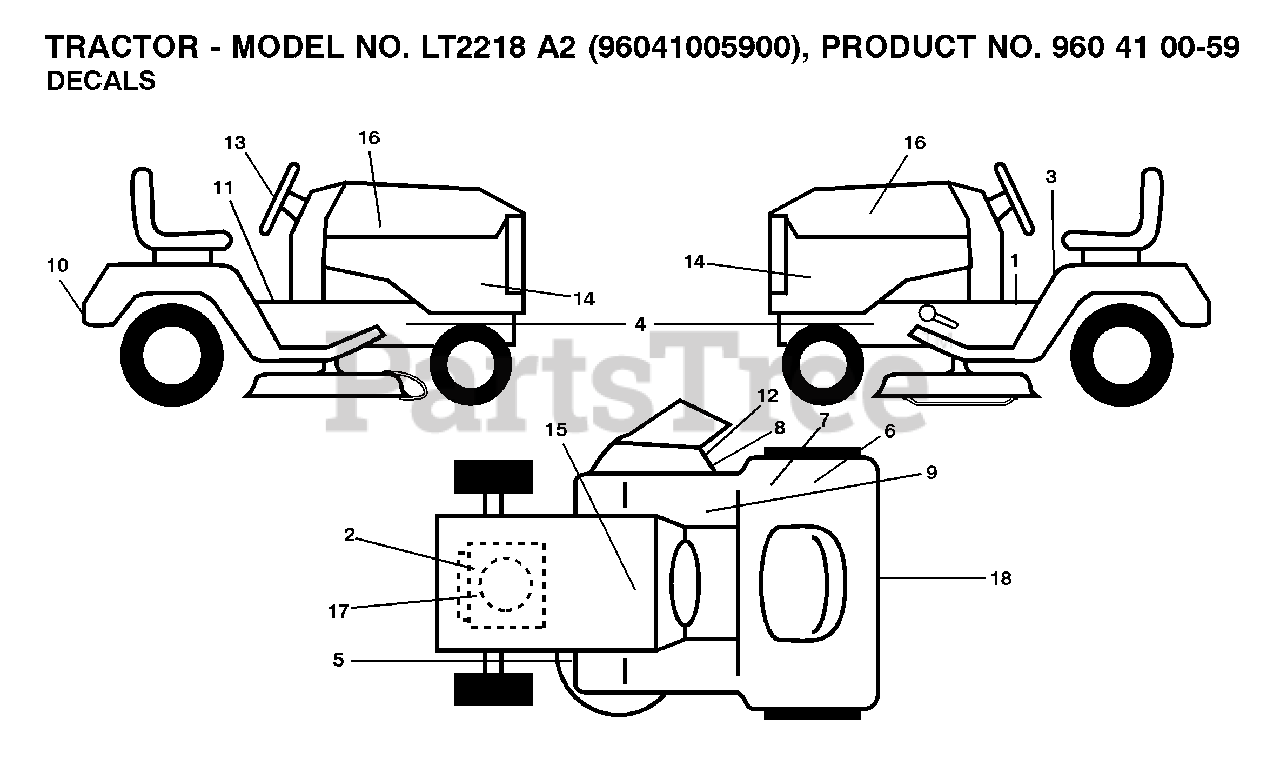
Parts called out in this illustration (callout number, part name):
1	DECAL PARK BRAKE
5	DECAL V BELT SCHEMATIC
7	DECAL.80 DBA.AUSTRALIA
8	DECAL, DEFLECT WARNING
12	DECAL.INTERNATIONL.CUTFINGER
15	DECAL BTRY SYMBOLS
